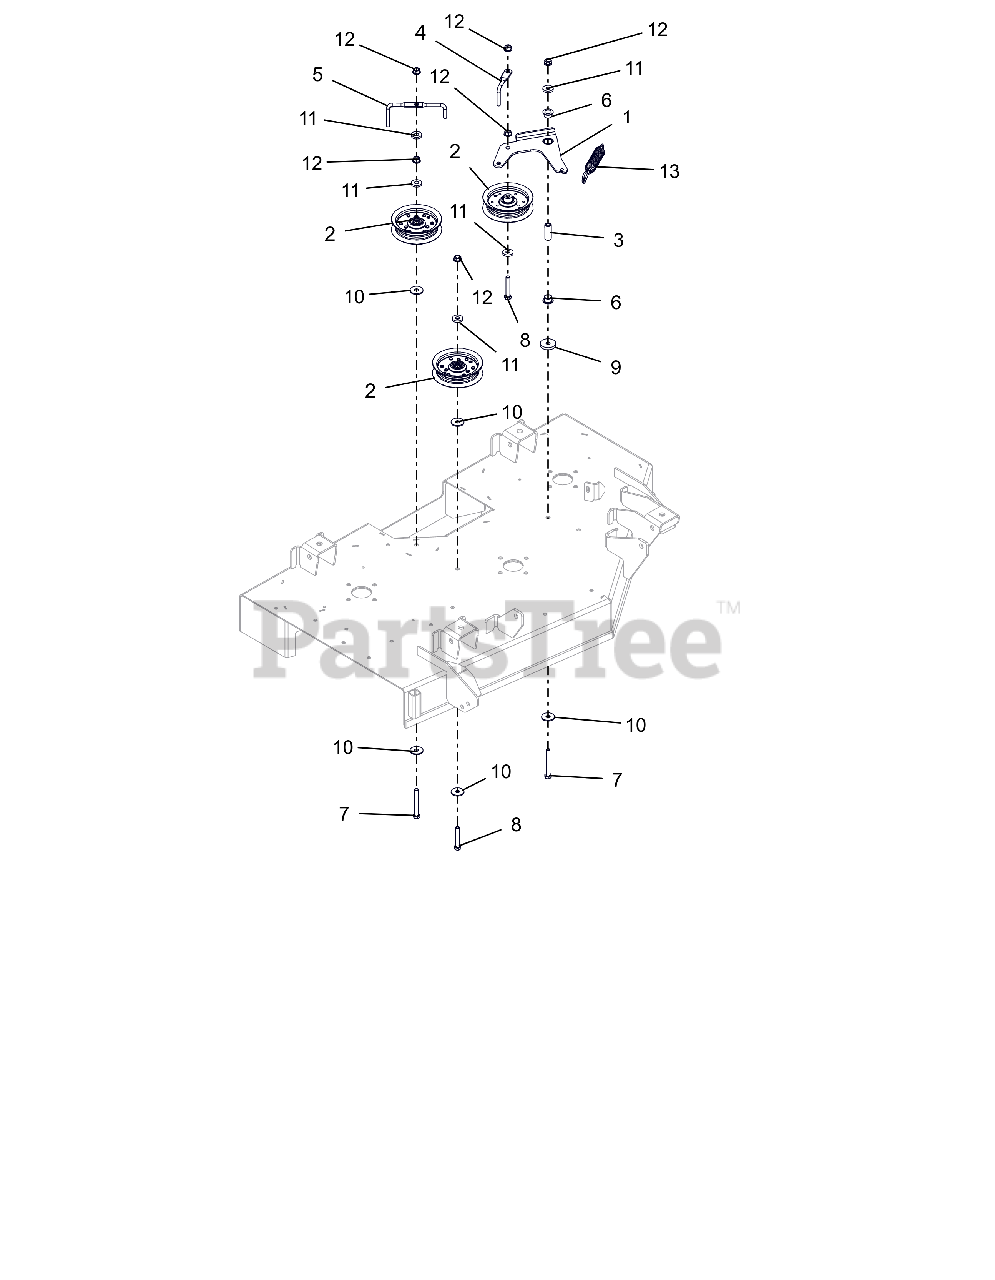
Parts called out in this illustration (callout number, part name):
1	WLDMT, IDLER ARM-42"
2	ASM, IDLER 4"
3	SPACER, .375IDX.625ODX1.66 PM
4	WIREFORM, BELT FINGER
5	WIREFORM, BELT FINGER
6	BSHG-FLG, .625X.750X.500X1.00
7	BLT-HEX .38-16X3.00 GR5 FTH YZ
8	@BLT-HEX .38-16X2.25 GR5 YWZC
9	WSHR,FLT STL.406X1.50X.245YWZC
10	WSHR FL STL .406X1.25X.10ZC120
11	WSHR-FL-STL .406X1.00X.188 YWZ
12	NUT-LK-TOP-FLG .38-16 ZC120
13	SG-TENS .135X.98X6.0 WLD 62
